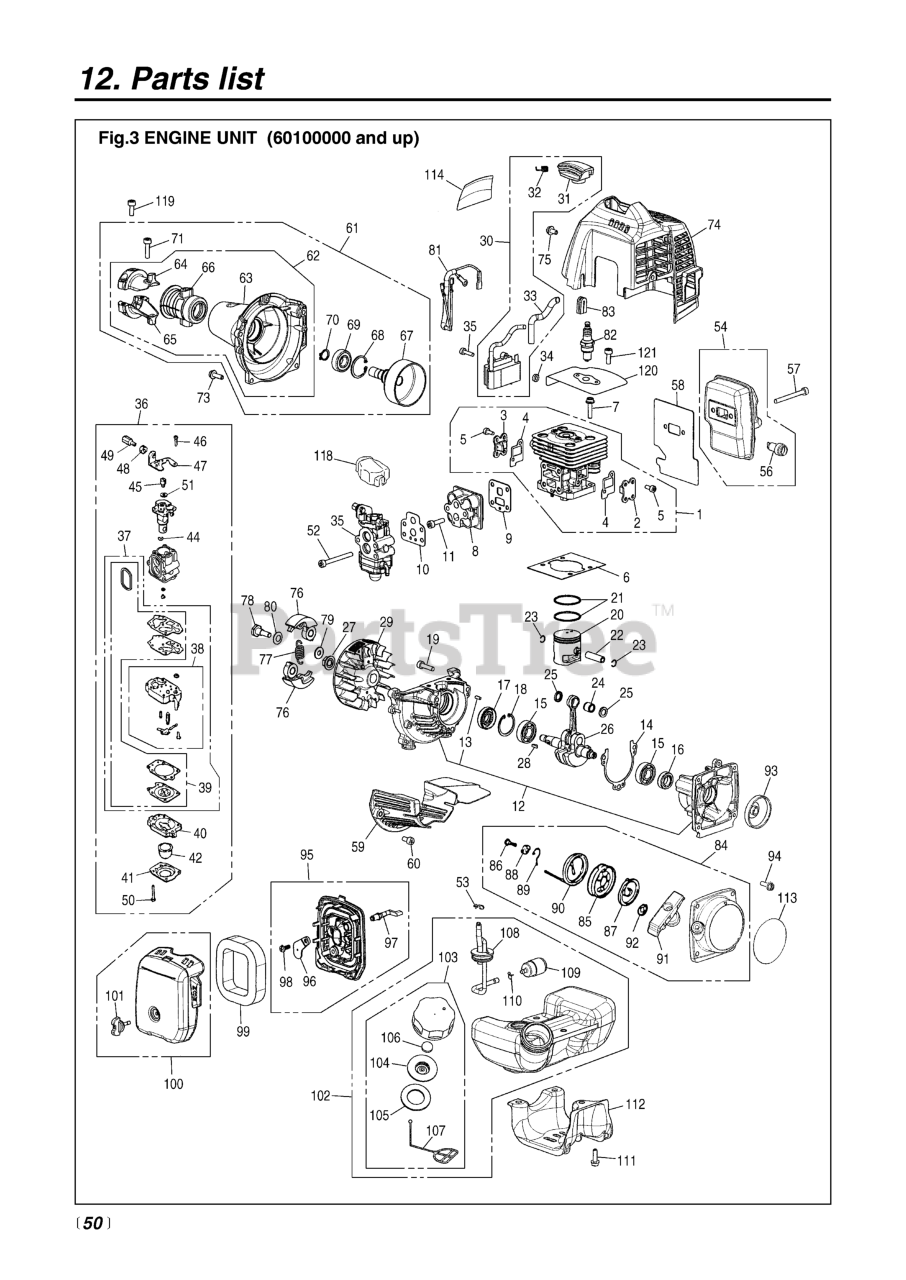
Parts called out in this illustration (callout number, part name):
1	CYLINDER-C
2	COVER, TR-S
3	COVER, TR-F
4	GASKET, TR
5	BOLT, TORX
6	GASKET, BASE
7	BOLT
8	INSULATOR
9	GASKET, INSULATOR
10	GASKET, CARB
11	BOLT, TORX
12	CRANKCASE-C
13	PIN
14	GASKET, CASE
15	BEARING
16	SEAL
17	SEAL, OIL (RPLS 1140-21220)
18	RING, SNAP, M28 x 1.2
19	BOLT (RPLS 2850-14220)
20	PISTON
21	RING, PISTON
22	PIN, PISTON
23	RING, SNAP (RPLS 1101-41320)
24	BEARING
25	WASHER
26	CRANKSHAFT-C
28	KEY
29	ROTOR
30	COIL-A
31	CAP (RPLS 4810-72110)
32	SPRING
33	TUBE
34	SPACER (RPLS -71260)
35	BOLT TORX
36	CARBURETOR ASSY
37	REBUILD KIT
38	BODY, PUMP
39	KIT, GASKET (REPLACES-06020)
40	BODY, PURGE
41	COVER, PUMP
42	PUMP, PRIMING
44	RING
45	SWIVEL
46	SCREW
48	NUT, CABLE ADJUSTER
49	SCREW, CABLE ADJUSTER
50	SCREW
51	WASHER
52	BOLT
53	CLIP
54	MUFFLER-A
56	ARRESTER
57	BOLT
58	GASKET, MUFFLER
59	PLATE
60	BOLT
61	HOUSING ASSY (RPLS T1551-31000
62	HOUSING COMP (RPLS. -31110)
64	BRACKET (A) (RPLS -31211)
65	BRACKET (B)
66	CUSHION (RPLS -31231)
67	DRUM (REPLACES 4810-31122)
68	RING, SNAP, M28 x 1.2
69	BEARING
70	RING, SNAP (RPLS 3130-13270)
71	BOLT (RPLS 2850-14220)
73	BOLT
74	COVER, ENGINE
75	BOLT (RPLS. T4950-51011)
76	SHOE
77	SPRING
78	BOLT
79	WASHER, FLAT (USE 182303)
80	WASHER (RPLS -51241)
81	CORD COMP.
83	GROMMET
84	RECOIL-A
85	REEL
86	SCREW
87	SPRING, SPIRAL
88	COLLAR
89	ARM
90	ROPE (REPLACES 4500-75160)
91	KNOB (RPLS -75420)
92	PLATE, STOPPER
93	PULLEY
94	BOLT, TORX
95	BODY ASSY (RPLS T1551-82100)
96	PLATE, CHOKE
97	LEVER
98	SCREW
99	ELEMENT
100	COVER-A (RPLS T1551-82200)
101	KNOB
102	TANK ASSY
103	CAP ASSY (RPLS -85201)
104	HOLDER (REPLACES -85230)
105	PACKING
106	FILTER
107	STOPPER
109	FILTER ASSY
110	CLIP (REPLACES 2841-31280)
111	BOLT
112	GUARD, TANK
113	LABEL, RECOIL
114	LABEL, COVER
118	COVER
119	BOLT
120	PLATE
121	BOLT
